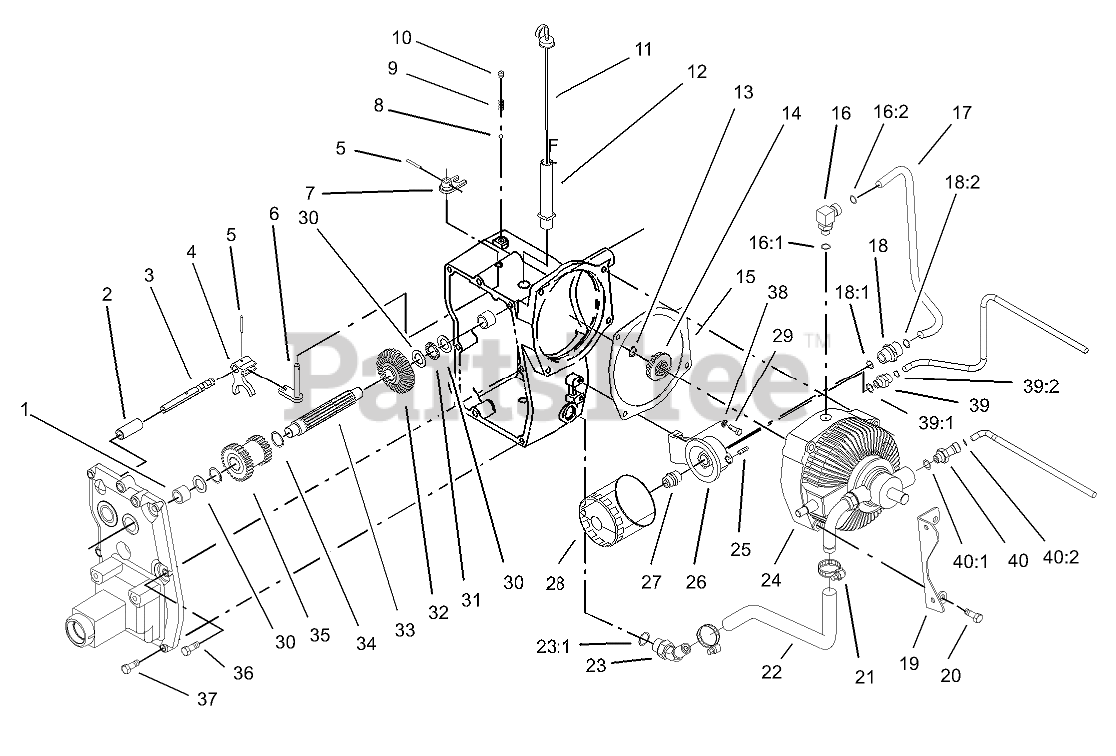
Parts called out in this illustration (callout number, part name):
1	BEARING-NEEDLE
2	TUBE-RAIL, SHIFTER
3	RAIL-SHIFT
4	FORK-HI / LO SHIFT
5	PIN-ROLL
6	ARM-SHIFTER
7	SHIFT-HI / LO
8	BALL-DETENT
9	SPRING-DETENT, SHIFT
10	SCREW-SET, HSH
11	DIPSTICK
12	TUBE-DIPSTICK
13	RING-SNAP, EXTERNAL
14	PINION-BEVEL
15	GASKET
16	FITTING -HYD, 90 DEGEE
16:1	O-RING
16:2	O-RING
17	TUBE-HYD
18	FITTING-STRAIGHT
18:1	O-RING
18:2	O-RING
19	PLATE-BRACKET, SUPPORT
20	SCREW-HH
21	CLAMP-DRIVE, WORM
22	HOSE-SUCTION
23	FITTING-HOSE
23:1	O-RING
24	TRANSMISSION-HYDRO
25	PLUG-PIPE
26	BASE-FILTER
27	FITTING
28	ASS'Y-OIL FILTER
29	SCREW-HH
30	WASHER-THRUST
31	BEARING-THRUST
32	GEAR-BEVEL
33	SHAFT-INPUT
34	RING-RETAINING
35	GEAR-HI / LO
36	SCREW-HH
37	SCREW-HH
38	WASHER-LOCK
39	FITTING-HYD. STRAIGHT
39:1	O-RING
39:2	O-RING
40	FITTING-HYD, 45 DEGREE
40:1	O-RING
40:2	O-RING
